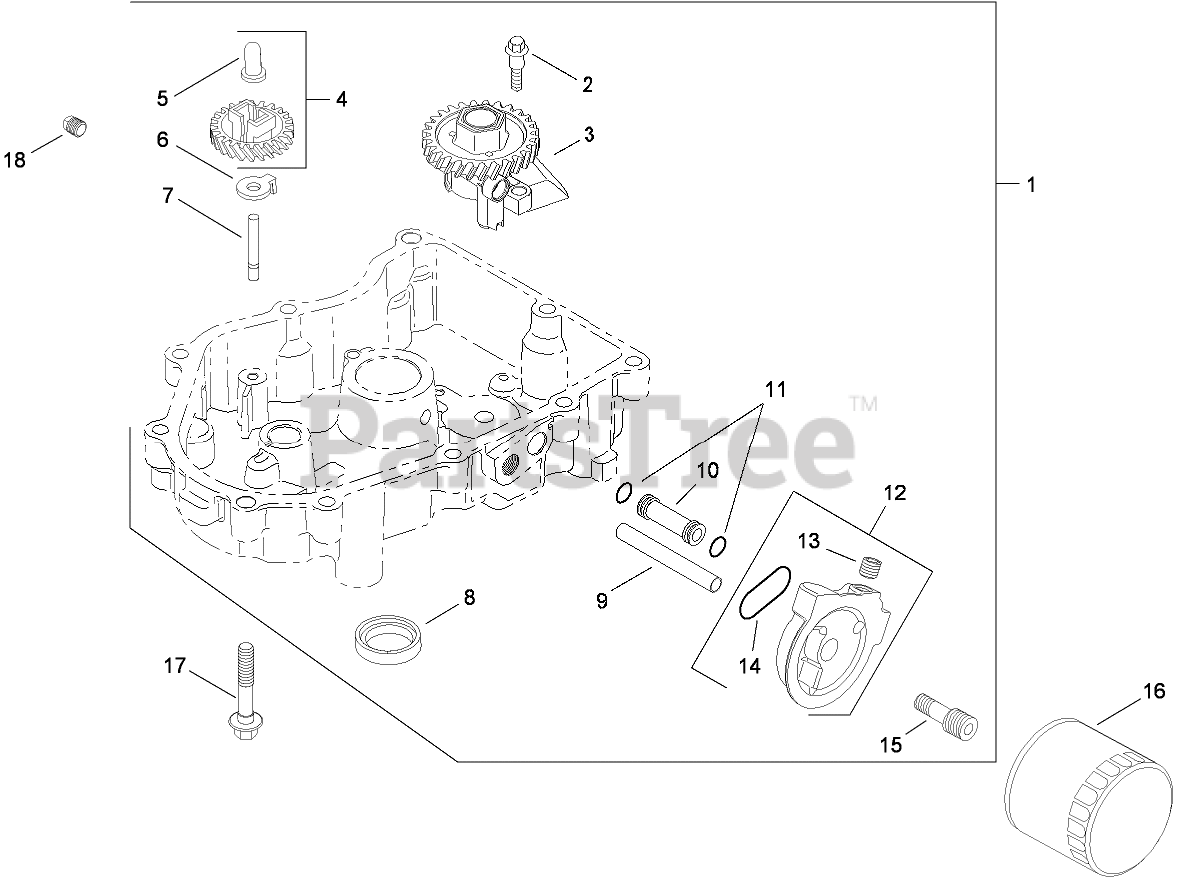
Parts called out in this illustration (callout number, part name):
1	OIL PAN ASM (INCLUDES 2-15)
2	SCREW-SHOULDER, THD FRM (M6x1.0x26.5)
3	OIL PUMP ASM
4	GOVERNOR GEAR KIT W/PIN (INCLUDES 5)
5	PIN-REGULATING, GOVERNOR
6	TAB-LOCKING
7	SHAFT-GEAR, GOVERNOR
8	SEAL-OIL (P-T-O END)
9	TUBE-FEED, OIL (FILTER TO PAN)
10	TUBE-FEED, OIL (PAN TO FILTER)
11	O-RING
12	ADAPTER OIL FILTER KIT (INCLUDES 13-14)
13	PLUG-PIPE, COUNTERSUNK (1/8)
14	O-RING
15	NIPPLE-FILTER, OIL
16	FILTER-OIL
17	SCREW-FLANGE (M8X1.25X45)
18	PLUG-PIPE, SQ HD (3/8)
